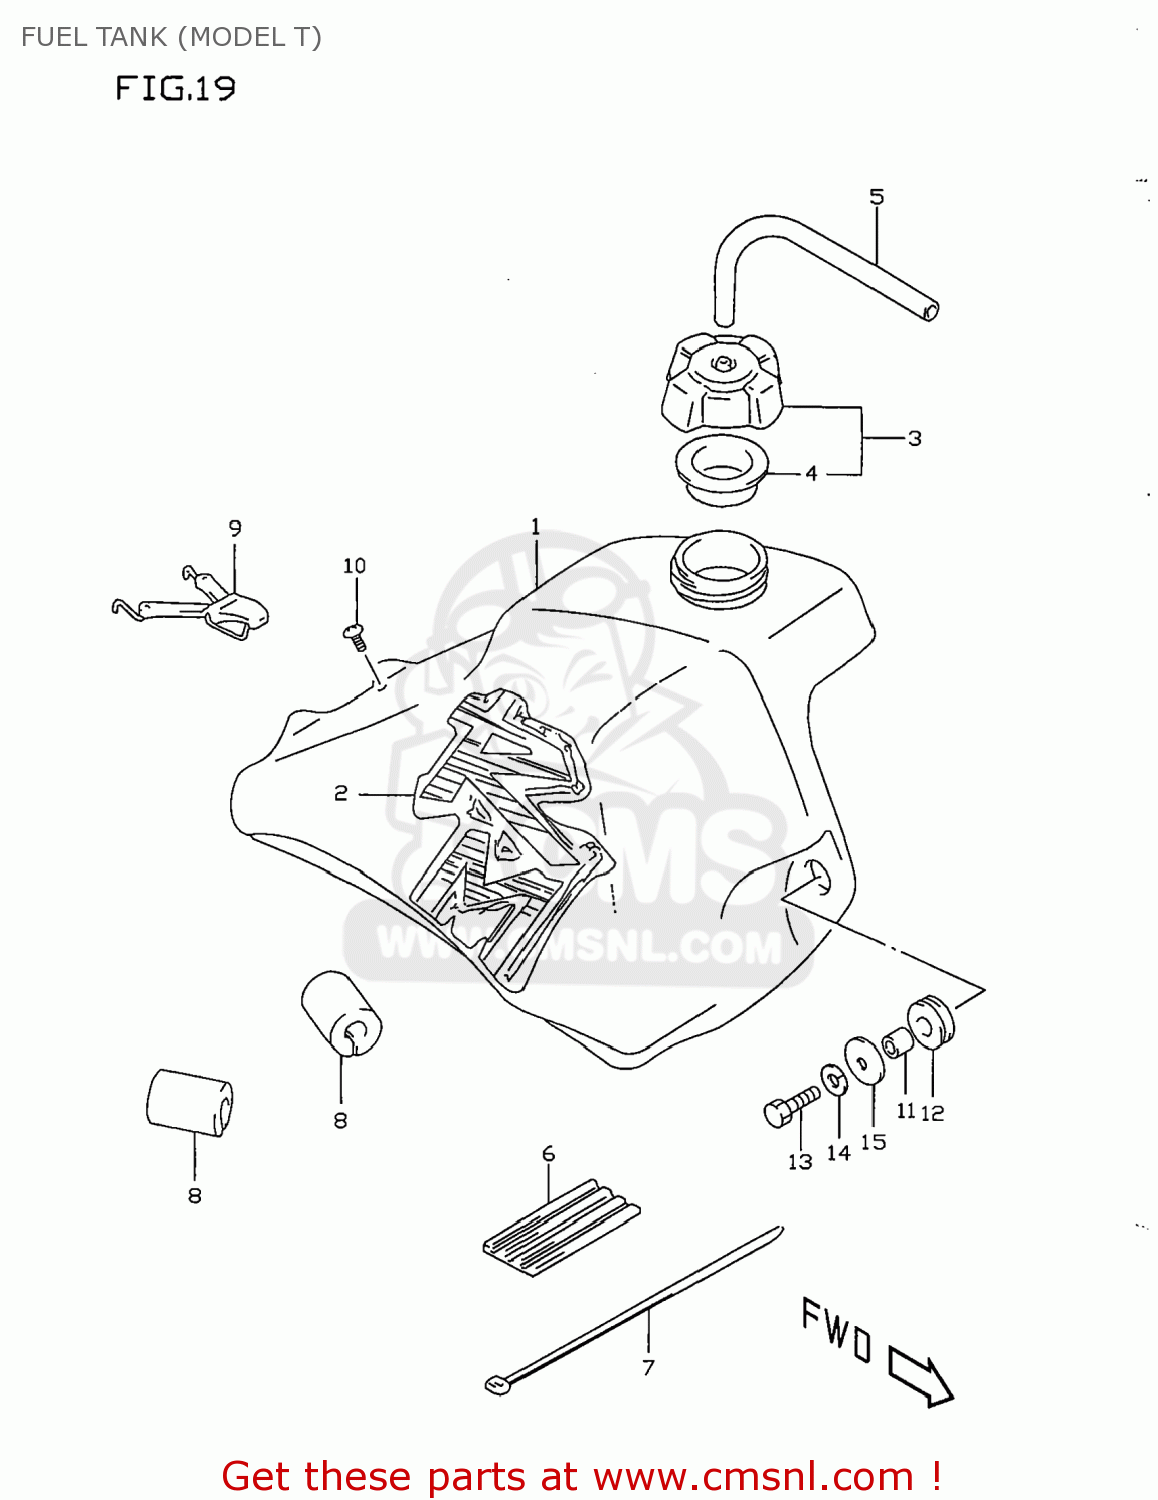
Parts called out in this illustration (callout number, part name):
1	TANK SET,FUEL
2	EMBLEM,FUEL TANK
3	CAP SET,FUEL TANK
4	GASKET,CAP (NAS)
5	HOSE(5X8.2X600)
6	CUSHION,FUEL TANK UPR FR
7	CLAMP
8	CUSHION,FUEL TANK UPR RR
9	BAND,FUEL TANK RR
10	SCREW
11	SPACER (6.8X10X11.5)
12	CUSHION
13	BOLT
14	LOCK WASHER
15	WASHER (6.5X24X1.6)
